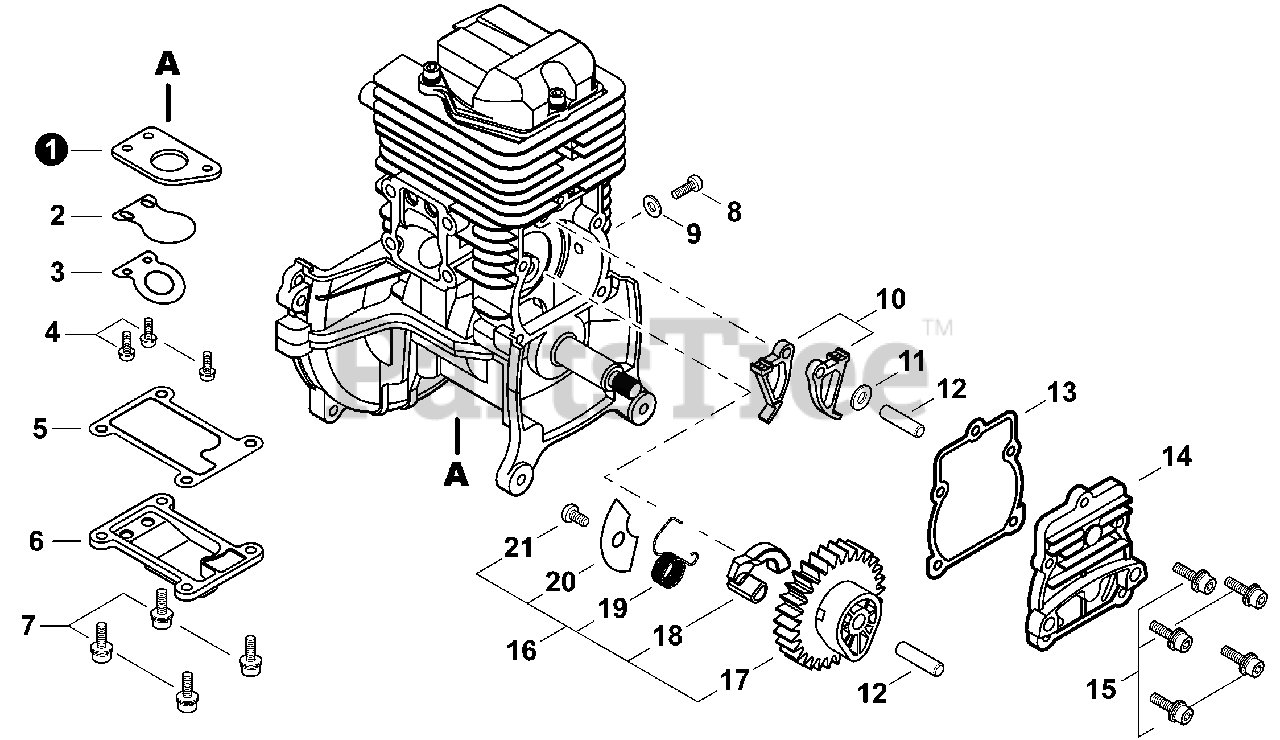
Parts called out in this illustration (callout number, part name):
1	PLATE, REED BACKING
2	VALVE, REED
3	STOP, REED VALVE
4	SCREW M3×10
5	GASKET, REED VALVE
6	COVER, REED VALVE
7	BOLT M4×12
8	SCREW M5
9	WASHER 10×5.5×2
10	FOLLOWER, CAM
11	WASHER 5MM
12	PIN, LOCATING 5×29.8mm
13	GASKET, CAM GEAR
14	COVER, CAM GEAR
15	BOLT M4×14
16	CAM GEAR ASSY
17	GEAR, CAM
19	SPRING, COIL
20	PLATE, COVER
21	SCREW, TAPPING 4×6
